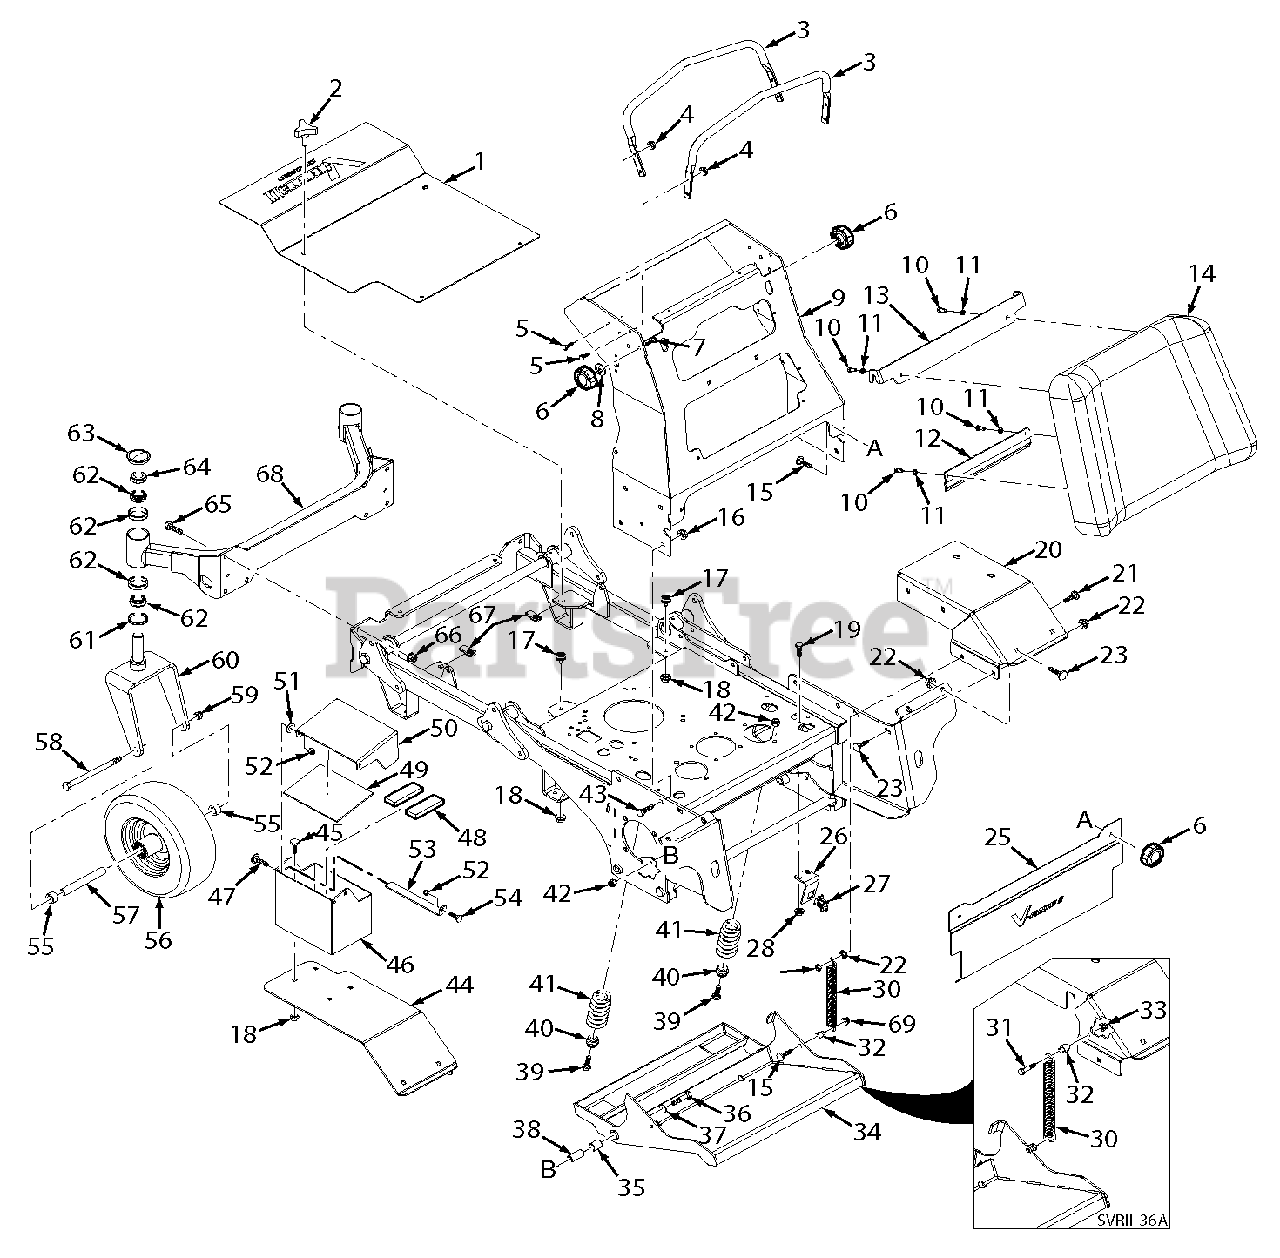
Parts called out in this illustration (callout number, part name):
1	Belt Cover w/Decals
2	Knob w/Stud
3	Reference Bar
4	Nut, Serrated Flange 5/16-18
5	Bolt, Hex Head 5/16-18 x 3/4"
6	Knob, 5/16-18
7	Bolt, Carriage 5/16-18 x 1"
8	Nut, Push-On 5/16
9	Handlebar Weldment, SVRII-36
9	Handlebar Weldment, SVRII
10	Bolt, Hex Head 5/16-18 x 3/4"
11	Lockwasher, 5/16"
12	Bracket, Knee Pad - Lower
13	Bracket, Knee Pad - Upper
14	Operator Pad Assy, SVRII-36
14	Operator Pad Assy, SVRII
15	Bolt, Carriage 5/16-18 x 3/4"
16	Nut, Spiral Lock 1/2-13
17	Rubber Bumper
18	Nut, Serrated Flange 5/16-18
19	Bolt, Hex Head 1/4-20 x 3/4"
20	Fender, RH
20	Fender, RH - SVRII-36
21	Bolt, Carriage 3/8-16 x 1-1/2"
22	Nut, Serrated Flange 3/8-16
23	Bolt, Carriage 3/8-16 x 3/4"
24	Mainframe Assy. - SVRII-36
24	Mainframe Assy. - SVRII
25	Guard, Foot - SVRII-36
25	Guard, Foot -SVRII
26	Switch Bracket, OPC Switch -SVRII-36
26	Switch Bracket, OPC Switch
27	Switch, Double Pole OPC - SVRII-36
27	Switch, OPC - SVRII
28	Nut, Serrated Flange 1/4-20
29	Nut, Flange Elastic Stop 3/8-16
30	Spring
31	Bolt, Hex Head 5/16-18 x 1-1/2"
32	Spacer
33	Nut, Elastic Stop 5/16-18
34	Footplate Assy, SVRII-36
34	Footplate Assy, SVRII
35	Bearing
36	Bolt, Hex Head 3/8-16 x 2"
37	Flatwasher, 3/8-.391 x .938 x .105
38	Spacer
39	Bolt, Hex Head 3/8-16 x 1-3/4"
40	Mount, Spring
41	Spring, Suspension Platform
42	Nut, Elastic Stop 3/8-16
43	Bolt, Hex Head Serrated Flange 1/2-13 x 1"
44	Fender, LH - SVRII-36
44	Fender, LH
45	Bolt, Carriage 5/16-18 x 3/4"
46	Battery Box, Lower
47	Bolt, Carriage 1/4-20 x 1/2"
48	Pad, Rubber
49	Insulation, Battery Cover
50	Battery Box, Upper
51	Flatwasher, 1/4-.312 x .750 x .065
52	Nut, Elastic Stop 1/4-20
53	Battery Box Latch
54	Bolt, Carriage 1/4-20 x 1/2"
55	Spacer, Caster Wheel
56	Caster Wheel Assy., 11 x 4 (36)
56	Caster Wheel Assy., 13 x 5 (48 / 52)
56	Caster Wheel Assy., 13 X 6.5 (61)
57	Sleeve, Caster Wheel (36)
57	Sleeve, Caster Wheel (48 / 52)
57	Sleeve, Caster Wheel (61)
58	Bolt, Hex Head 1/2-13 x 6-1/2" (36)
58	Bolt, Hex Head 1/2-13 x 7-1/2" (48 / 52)
58	Bolt, Hex Head 1/2-13 x 9-1/2" (61)
59	Nut, Elastic Stop 1/2-13
60	Yoke Weldment (36)
60	Yoke Weldment (48 / 52)
60	Yoke Weldment (61)
61	Seal, 2" x 1.625 Bore
62	Bearing w/ Race
63	Cap, Grease
64	Nut, Elastic Stop 1" - 14 Jam
65	Bolt, Hex Head 7/16-14 x 1-1/4"
66	Nut, Elastic Stop 7/16-14
67	U-Nut, 3/8-16
68	Caster Support Weldment (36)
68	Caster Support Weldment (48)
68	Caster Support Weldment (52)
68	Caster Support Weldment (61)
69	Nut, Flange Elastic Stop 5/16-18
